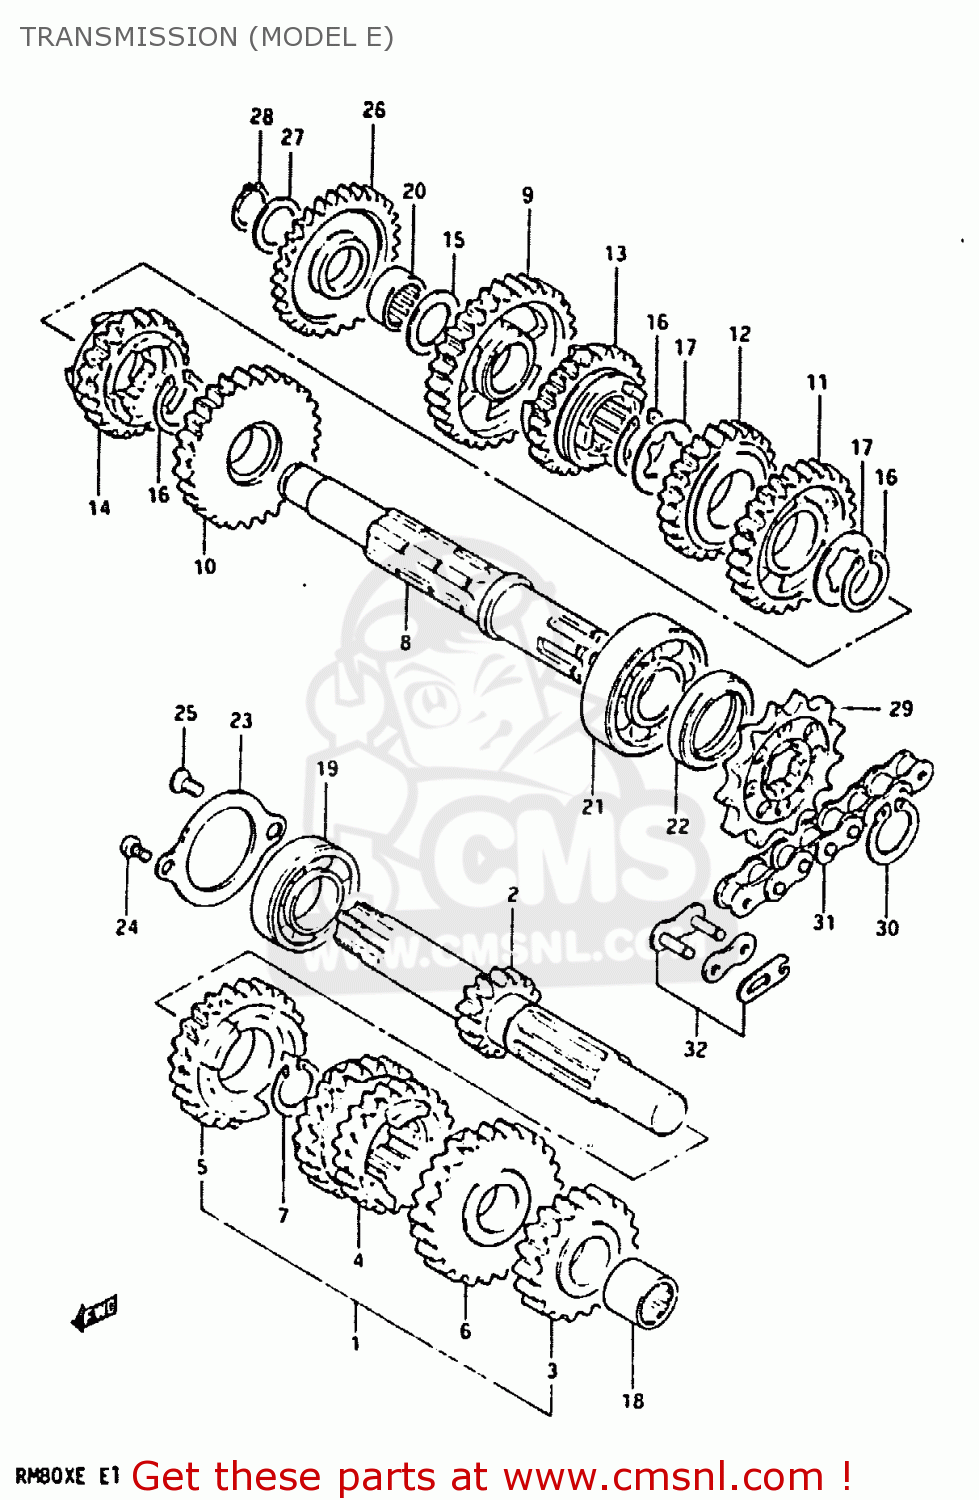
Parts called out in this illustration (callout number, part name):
1	SHAFT ASSEMBLY,COUNTER
2	SHAFT,COUNTER
3	GEAR,SECOND DRIVE
4	GEAR,THIRD & FOURTH DRIVE
5	GEAR,FIFTH DRIVE
6	GEAR,SIXTH DRIVE
7	CIRCLIP
8	SHAFT,DRIVE
9	GEAR,FIRST DRIVEN
10	GEAR,SECOND DRIVEN
11	GEAR,THIRD DRIVEN
12	GEAR,FOURTH DRIVEN
13	GEAR,FIFTH DRIVEN
14	GEAR,SIXTH DRIVEN
15	WASHER
16	CIRCLIP
17	WASHER,LOCK
18	ROLLER BEARING (13X19X1
19	BEARING
20	BEARING(15X21X12)
21	BEARING
22	OIL SEAL (20X35X5)
23	RETAINER,CNTR SHAFT BEARING
24	SCREW
25	SCREW
26	GEAR,KICK STARTER IDLER(NT:26)
27	THRUST WASHER
28	CIRCLIP
29	SPROCKET,ENGINE
30	CIRCLIP
31	CHAIN ASSEMBLY,DRIVE
32	JOINT,CHAIN
